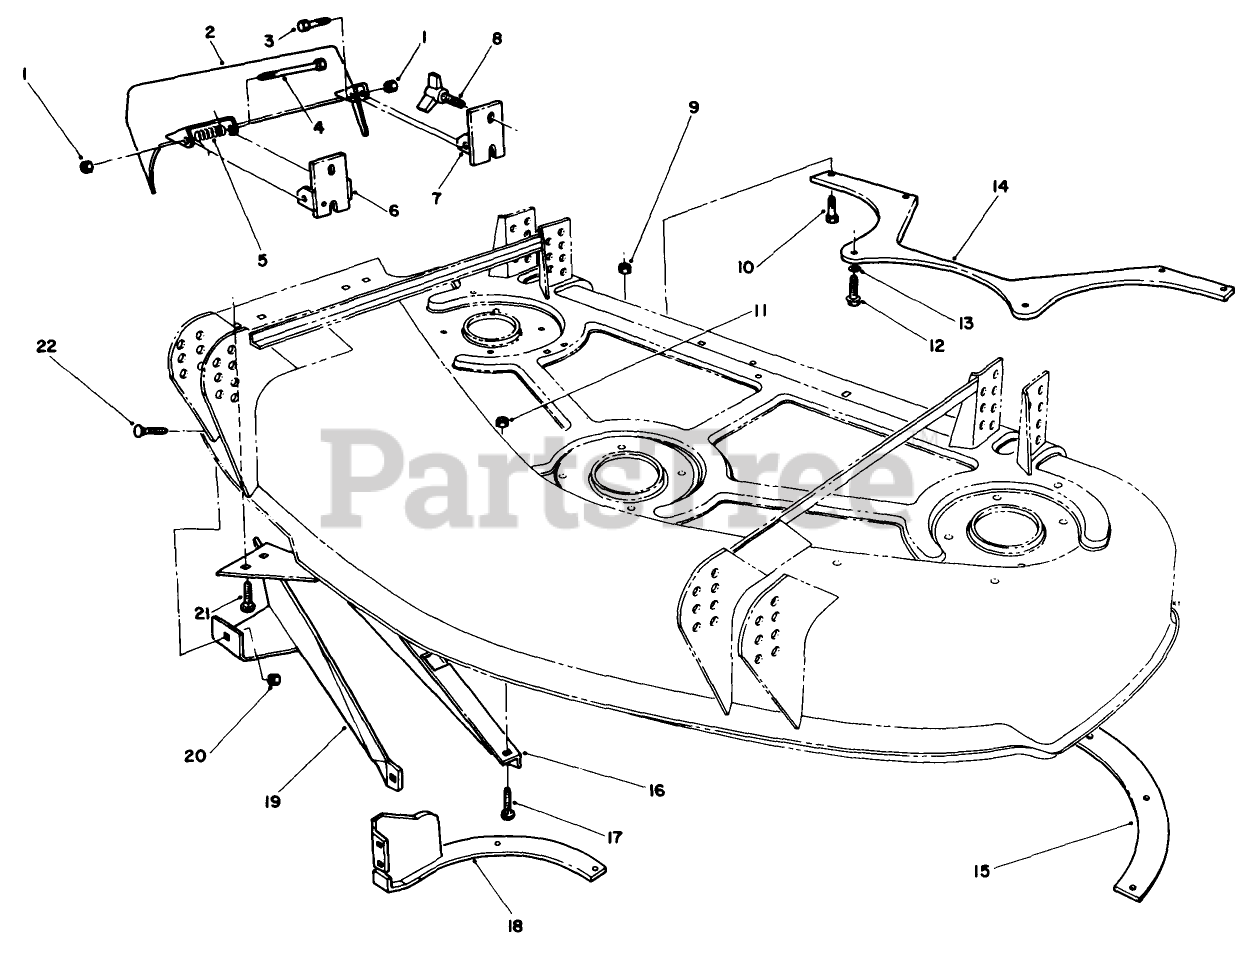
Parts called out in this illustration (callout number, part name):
1	NUT-HEX
3	SCREW-HH
4	SCREW-HH
5	SPRING
9	NUT-LOCK, NI
10	SCREW-HH
11	NUT-KEPS
12	Screw
13	WASHER-FLAT
17	SCREW-CARR
20	NUT-KEPS
21	BOLT-CARR
